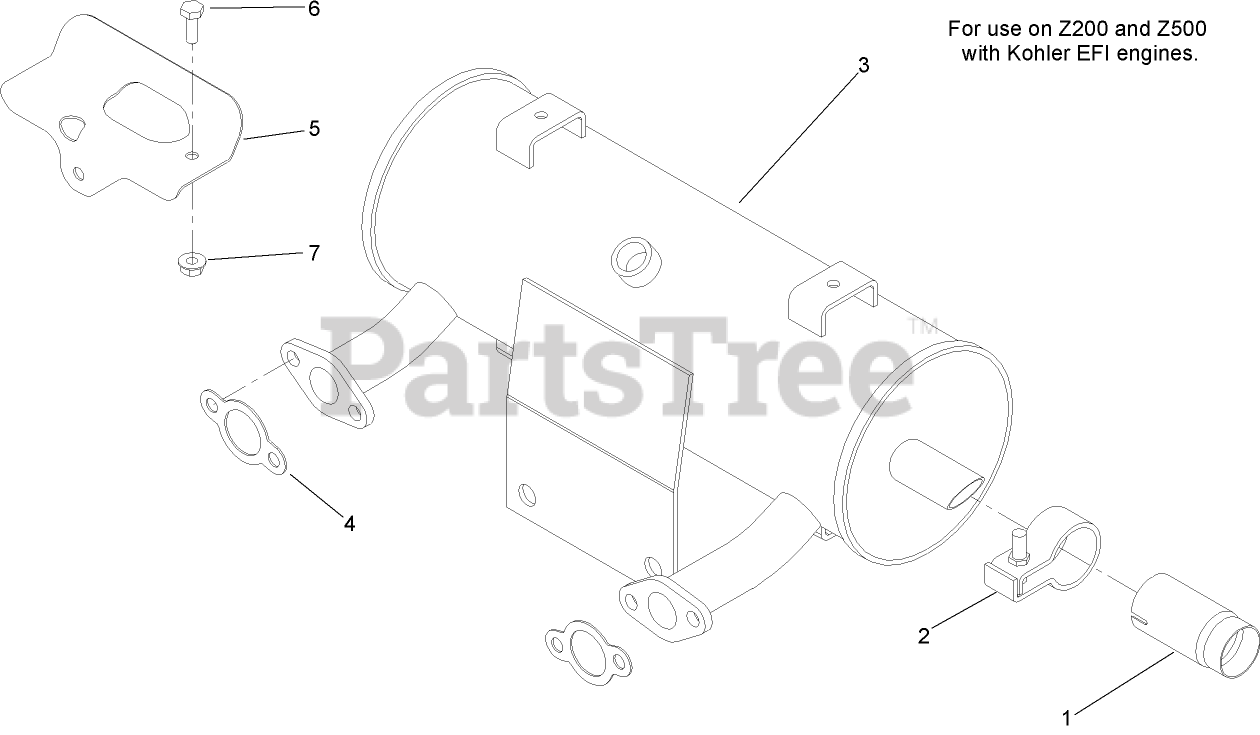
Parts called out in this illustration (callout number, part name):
1	ARRESTER-SPARK
2	CLAMP-MUFFLER
3	MUFFLER
4	GASKET-EXHAUST
5	SHIELD-HEAT, CABLE
6	SCREW-HH
7	NUT-HF
